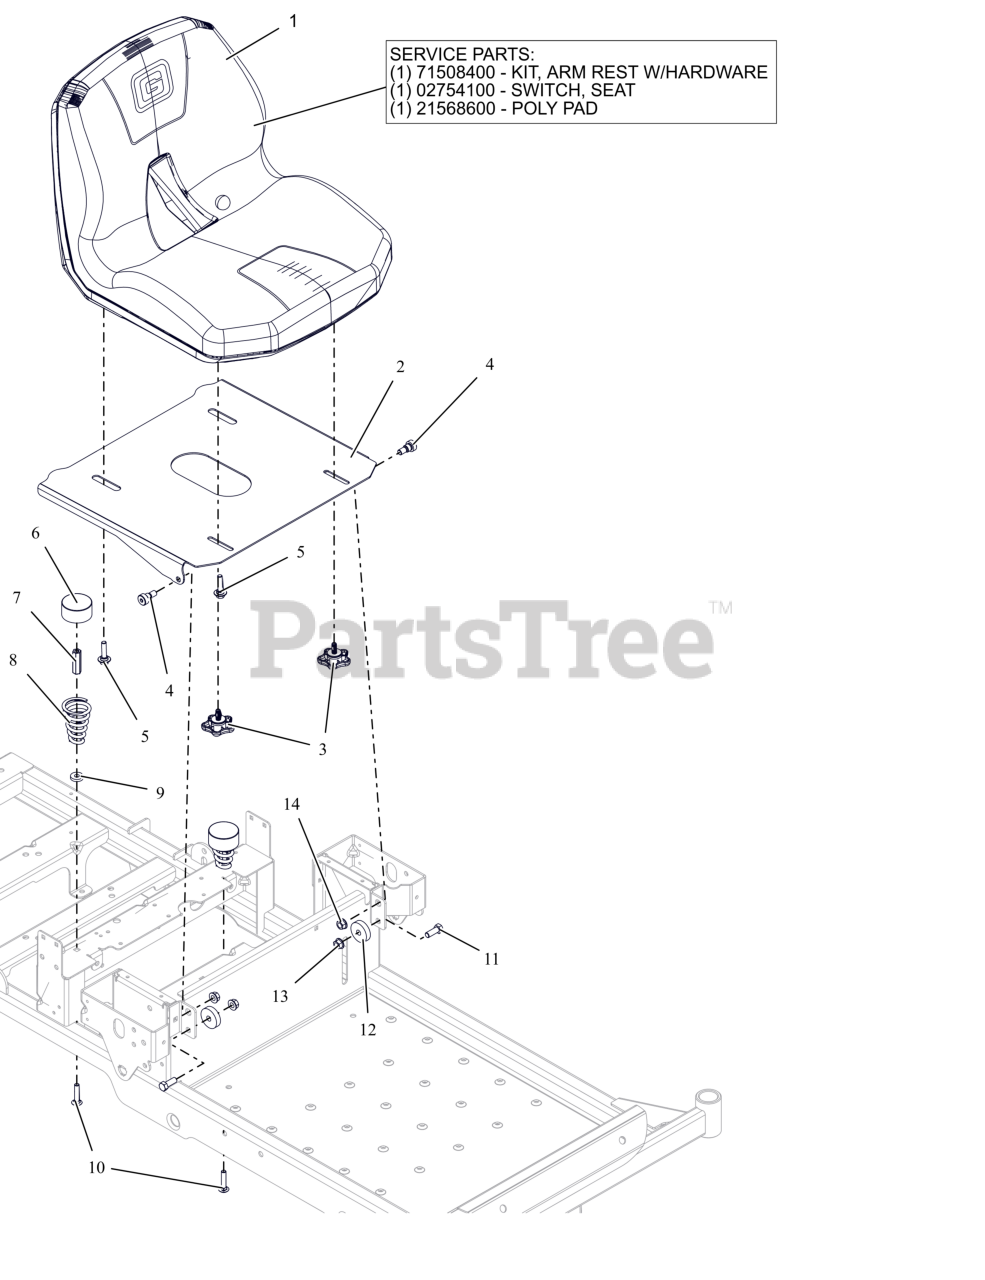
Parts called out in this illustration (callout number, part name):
1	SEAT, ZT
1	KIT- ARMREST - EDGE
1	SWITCH- SNAP MTG N.O.
1	POLY PAD - ZTX SEAT
2	PLATE- SEAT
3	KNOB, WING STUDDED
4	BLT-SHLDR .38-16X.38 SKH
5	BLT, SHLDR .31-18 X .175
7	NUT, COUPLING .31-18X1.75 ZCC
8	SPRING, SEAT
9	WSHR, FLT .328X.870X.179 ZCC
10	BLT,RHSN .31-18X1.50 G5 ZCC
11	BLT,HEX .38-16X1.00 G5 ZCC
12	SPACER, .39 X 1.50 X .380
13	NUT-LK-CTR-FLG .375-16 GF ZCC
14	NUT-LK-TOP-FLG .38-16 ZC120
